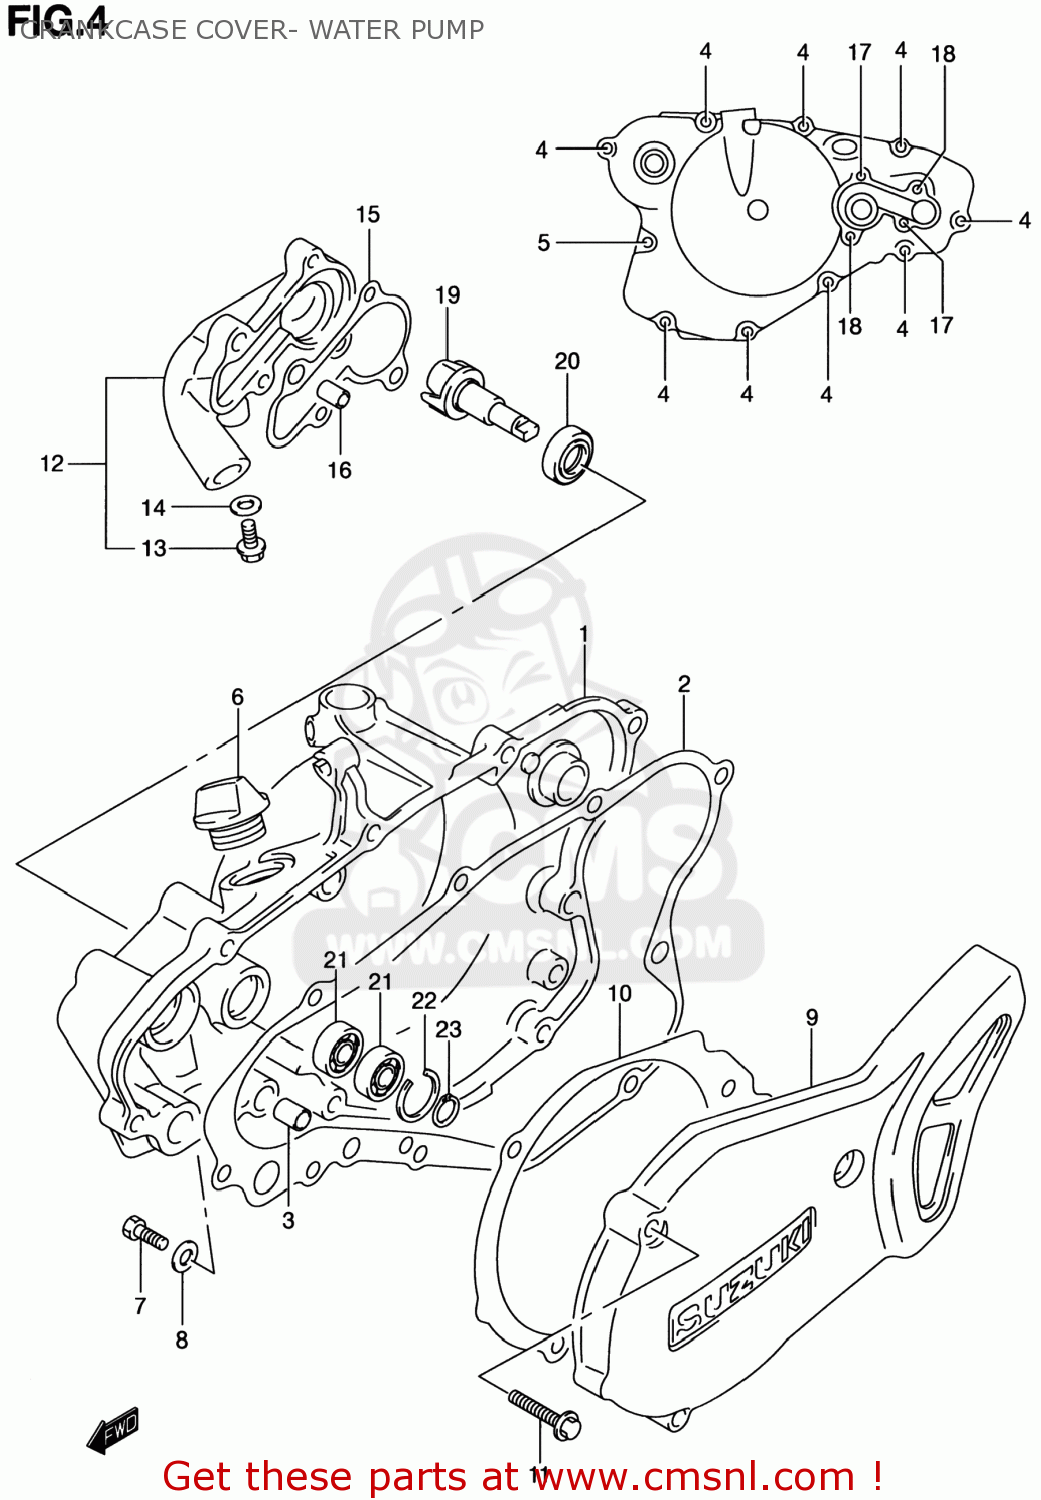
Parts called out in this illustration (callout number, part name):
1	COVER,CLUTCH
2	GASKET,CLUTCH COVER (NAS)
3	PIN
4	SCREW
5	BOLT
6	PLUG SET
7	SCREW(6X10)
8	GASKET(6.2X11X1).2 (NAS)
9	COVER,MAGNETO
10	GASKET,MAGNETO COVER (NAS)
11	SCREW
12	CASE,WATER PUMP
13	BOLT
14	WASHER
15	GASKET,WATER PUMP CASE (NAS)
16	PIN
17	SCREW
18	BOLT,G/S SWITC
19	IMPELLER,WATER PUMP
20	SEAL,WATER PUMP OIL
21	BEARING
22	CIRCLIP
23	CIRCLIP
